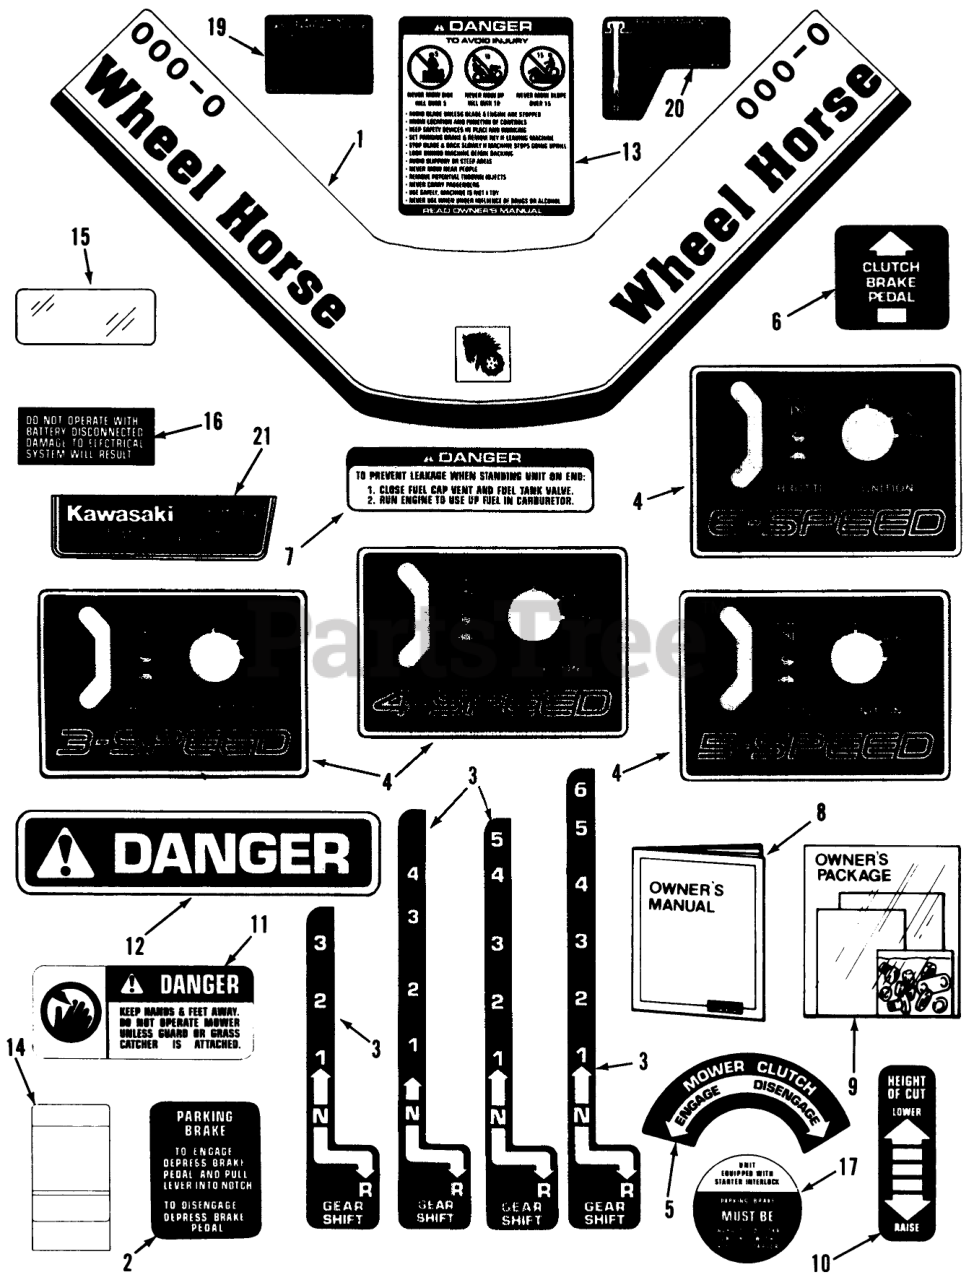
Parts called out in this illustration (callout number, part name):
1	Front Steering Shroud Decal 108-3 Only
2	DECAL PARKING BRAKE
3	DECAL SHIFT
4	DECAL 3SPD
5	DECAL MOWER CLUTCH
6	DECAL CLUTCH & BRAKE
7	DECAL-DANGER
8	Owner-s Manual
9	Loose Parts Package 108-3 Only
10	DECAL-HOC
11	Danger Decal
12	Danger Decal
13	DECAL-DANGER
14	Decal-Maintenance
15	DECAL-OVERLAY
16	DECAL ELECT SYSTEM
17	DECAL-ENGINE START
19	Decal-Engine Air Cleaner
20	Decal-Engine Oil Maintenance
21	Decal-FB460V
